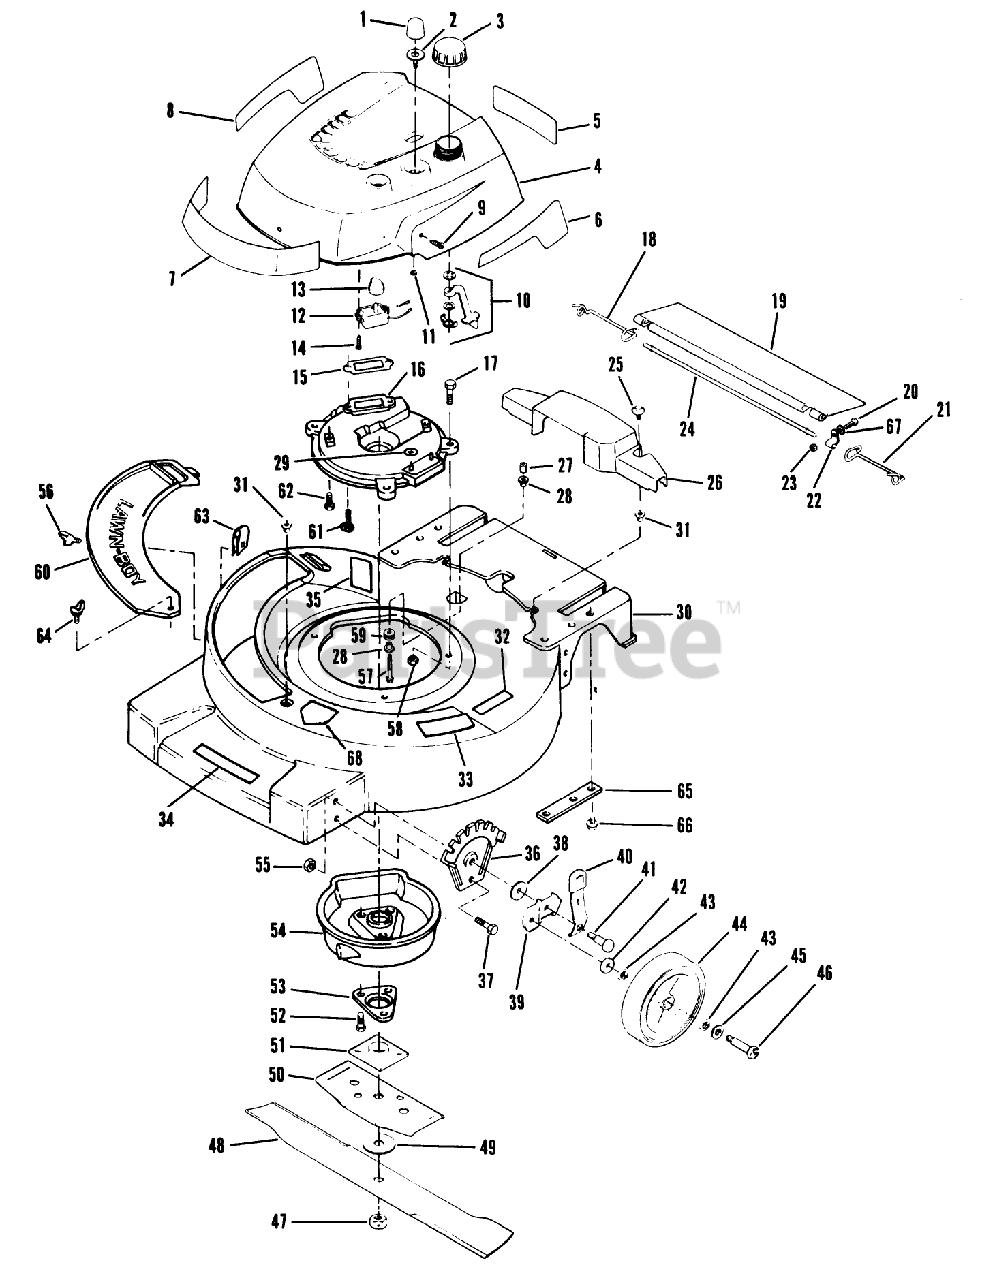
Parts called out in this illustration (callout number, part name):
9	SCREW S
11	LOCKNUT S
13	SWITCH KNOB
16	PLATE,MUFFLER F
18	SPRING;TRAILING SHIELD RH
21	SPRIG T/SHLD ASOC
23	LOCKNUT E
25	SCREW SEMS TRM HEX HD
28	SPACER ECK PRES
33	PAD FOOT
42	WASHER WROUGHT
46	BOLT WHEEL
47	NUT-BLADE
51	PLATE AND COLLAR ASM
53	SUPPORT F
55	LOCKNUT
58	NUT-LOCK F
61	SCREW V
64	WING SCREW LAWRE
67	WASHER F
